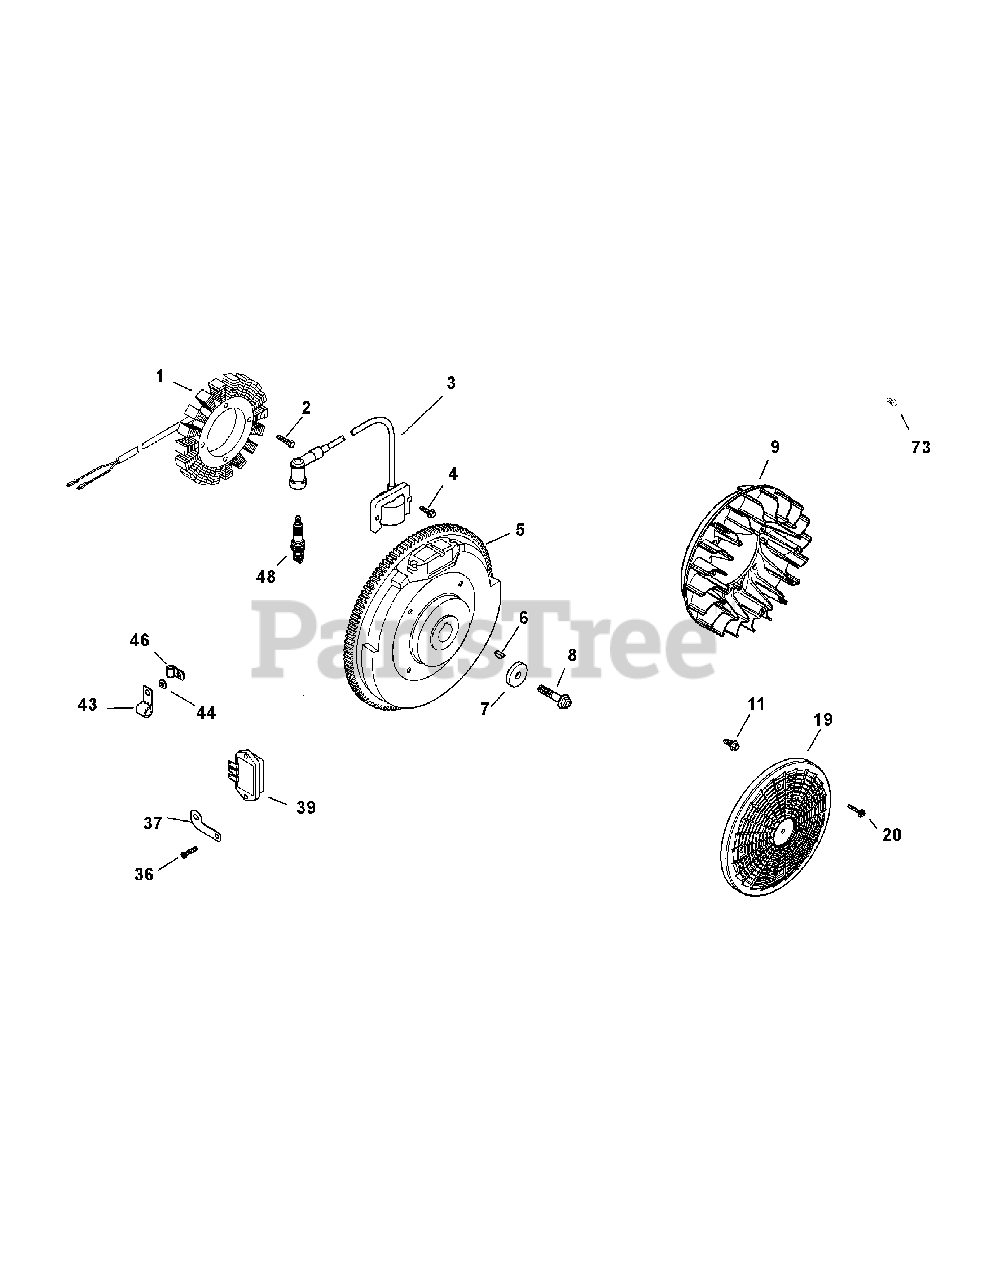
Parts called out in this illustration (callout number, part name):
1	Kit, 15 / 20 Amp Stator
2	Screw, Thd Frm M5X0.8X25
3	Kit, Module Igntn (Cdi Fixed)
4	Screw, Flg Thd Frm M5X.8X20
6	Key, 3/16" X 5/8"
7	Washer, Flat 13/32"
8	Screw, Flg M10X1.5X4
9	Fan
11	Bolt, Shoulder
19	Screen,Grass Low Prfle W/O Hole
20	Screw, Sems Dog Point
36	Screw, Hex Flange Hi-Lo
37	Bracket, Ground Strap
39	Regulator/Rectifier
43	Clip, Cable
44	Washer, Flat 1/4" (O.D. 1/2")
48	Spark Plug (Pro Series)
73	Screw, Wsh Hd Tap #8-18X1/2"
